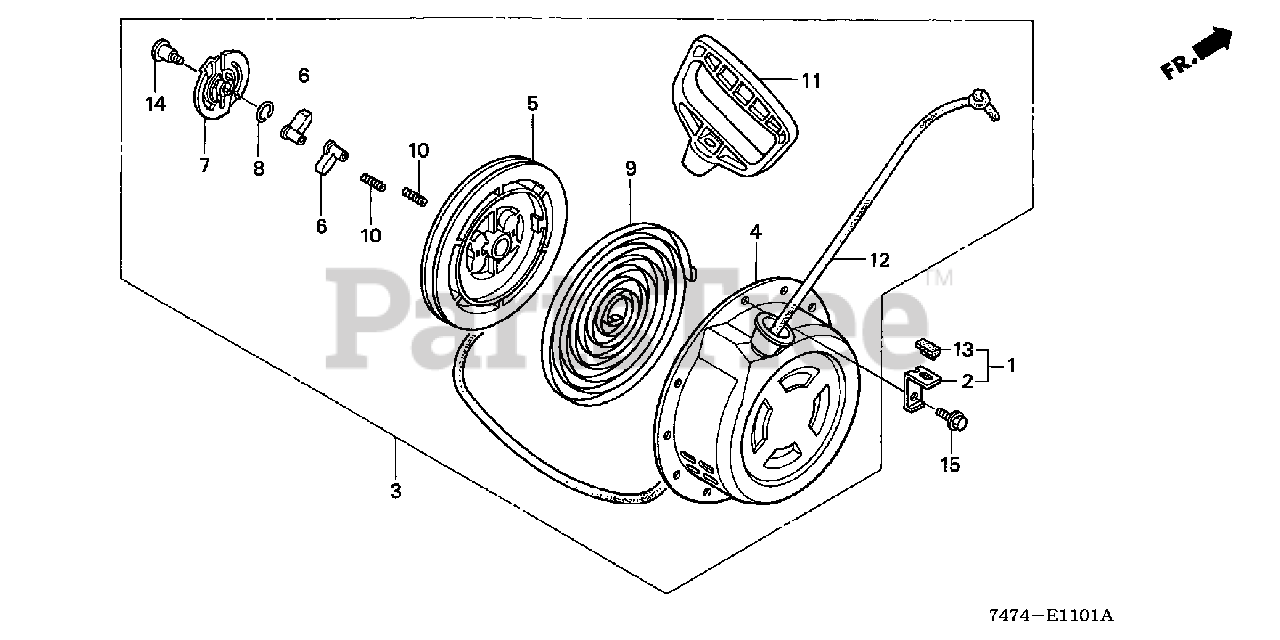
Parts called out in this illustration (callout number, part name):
1	STAY ASSY., FUEL TANK
2	STAY, FUEL TANK
3	STARTER ASSY., RECOIL
4	CASE, RECOIL STARTER
5	REEL, RECOIL STARTER
6	RATCHET, STARTER
7	GUIDE, RATCHET
8	SPRING, FRICTION
9	SPRING, RECOIL STARTER
10	SPRING, RETURN
11	GRIP, STARTER
12	ROPE, RECOIL STARTER (#5X73") (NA USE ALT:08550-ZG921-11)
13	STOPPER, DISCHARGE GUARD
14	SCREW, SETTING
15	BOLT, FLANGE (6X10)
